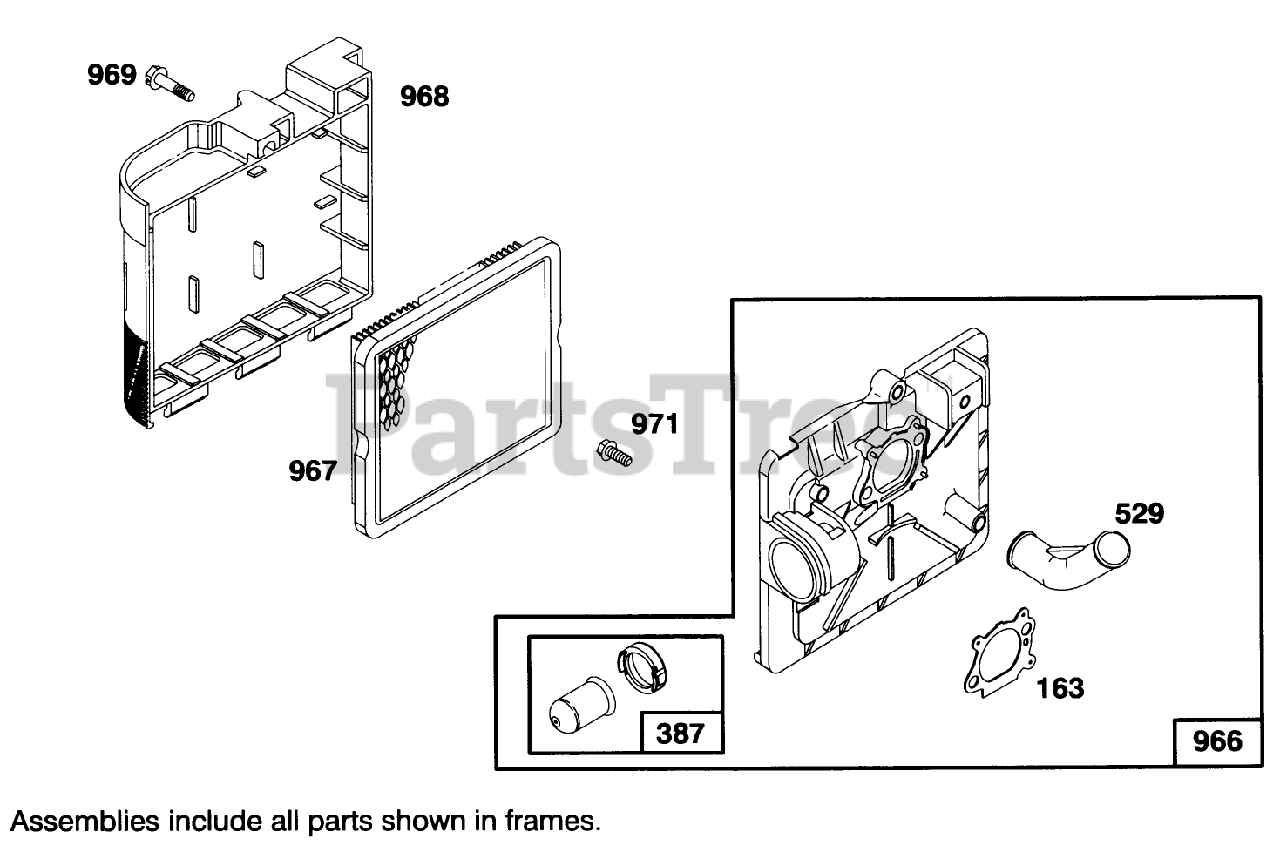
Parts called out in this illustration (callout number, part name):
163	Gasket-Cleaner, Air
387	CarburetorPrimer
529	Grommet
966	Base-Primer, Air Cleaner
967	Filter-Air Cleaner, Cartridge
968	Air Cleaner Cover
969	Screw-Cover Mt.
971	Screw-Air Cleaner
